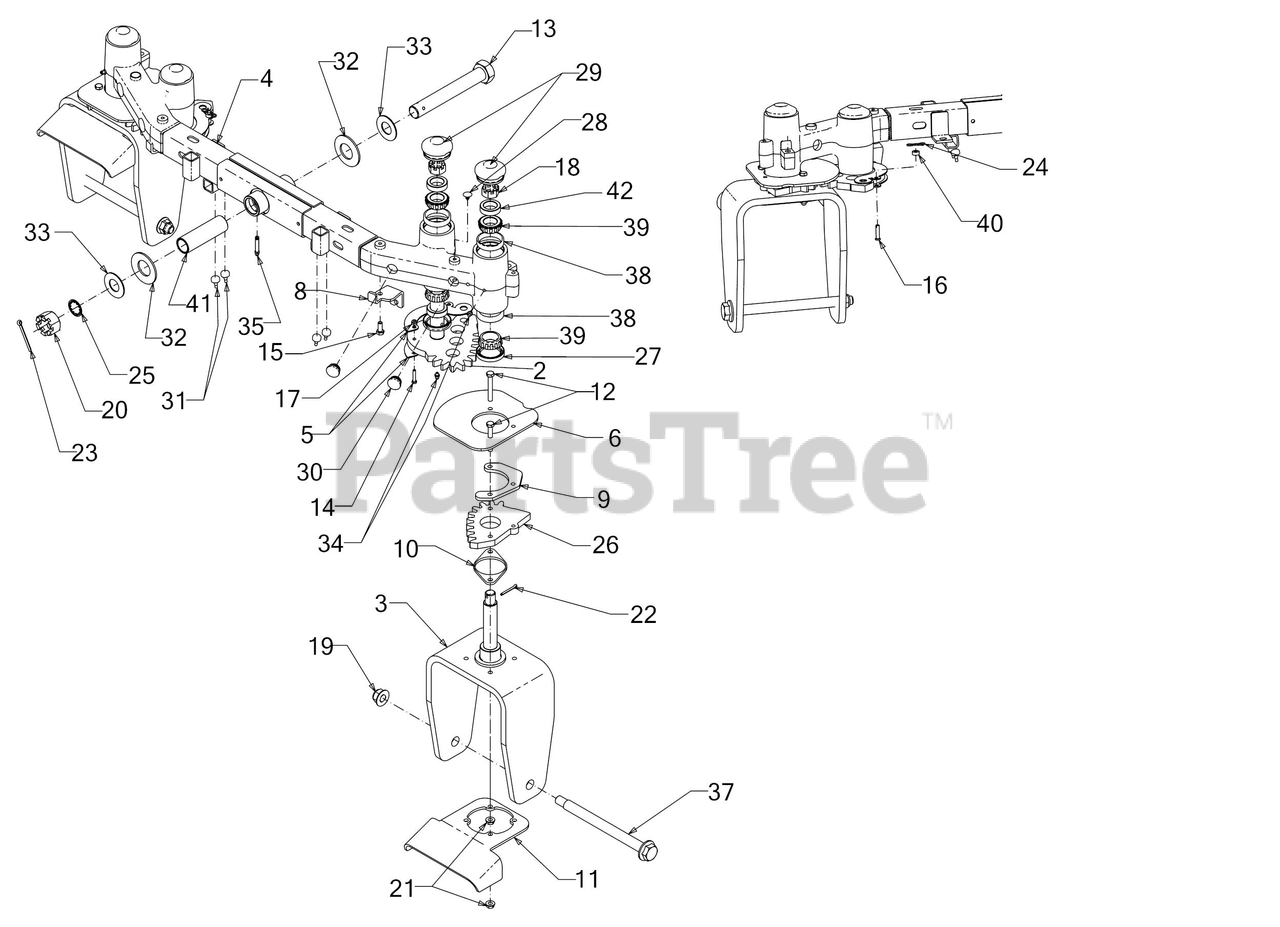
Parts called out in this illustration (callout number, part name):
2	STEERING GEAR (RH)
3	FRONT YOKE ASSEMBLY (STEERING)
4	AXLE ASSEMBLY
5	CABLE GEAR MOUNTING BRACKET
8	CABLE MOUNTING BRACKET (RH)
9	GEAR SPACER PLATE
10	LOWER GEAR SPACER PLATE
11	WHEEL DEFLECTOR BRACKET
12	HEX SCREW 5/16-18 x 2.25 GR5
13	HEX HEAD SCREW 1-14 X 7 GR5
14	SCREW #10-24 x 1.00 GR5.1
15	SCREW 5/16-18 x .750
16	CLEVIS PIN .25 x 1.00
18	HEX NUT CASTLE 3/4-16
19	FLANGE LOCK NUT
20	CASTLE NUT 1.0-14 GR5
21	HEX FLANGE NUT
22	COTTER PIN-5/32 DIA
23	COTTER PIN
24	BOW TIE COTTER PIN 1/4-5/16
25	RETAINING RING
26	STEERING GEAR YOKE
28	RATCHET CLIP
29	AXLE GREASE CAP
31	BUMPER, .62 DIA x .3
32	BELL WASHER 1.25ID x 2.5 x .180
33	FLAT WASHER 1.0 x 2.0 x .075
34	GREASE ZERT 1/4-28
35	GREASE FITTING
37	SHOULDER BOLT .750 X 8.175:5/8-11
38	BEARING CUP
39	BEARING CONE
